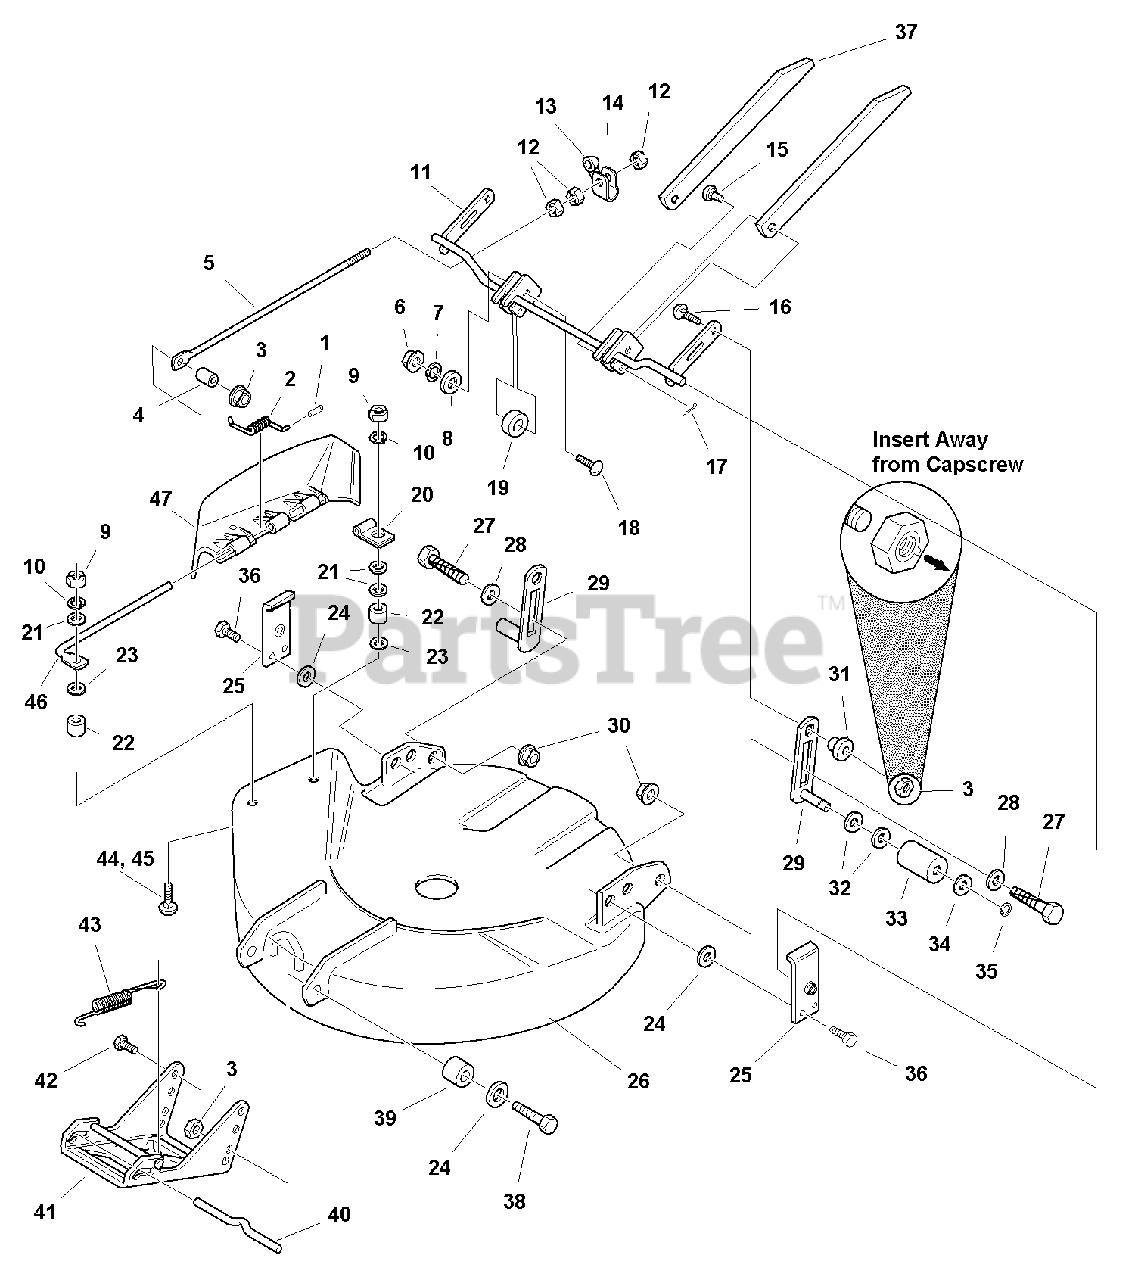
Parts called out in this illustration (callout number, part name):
1	CAP, Spring End
2	SPRING, Torsion
3	NUT, Hex, ALUM Lock, 3/8
5	ROD, Adjustment
6	NUT, Hex, 5/16-18
7	LOCKWASHER, 5/16
9	NUT, Hex, 1/4-20 ESNA
11	ARM ASSEMBLY, Mower
12	JAMNUT, Hex, 3/8-16
13	SPACER
15	PIN, Locking
16	CARRIAGE BOLT, 3/8-16 x 1-1/2
17	PIN, Retaining
18	CARRIAGE BOLT, 5/15-18 x 1-1/4
21	WASHER, Plain (1 Required for Export)
22	SPACER (Export)
23	PUSHNUT, 1/4
24	WASHER, Flat, 3/8
25	PLATE, Pivot Support
26	HOUSING ASSEMBLY, 30" (Orange)
26	HOUSING ASSEMBLY, 30" (Red)
26	HOUSING ASSEMBLY, 30" (Black)
27	BOLT, Shoulder, 3/8-16 X 1.34
28	WASHER, Flat
29	SUPPORT ASSEMBLY, Roller
30	NUT, Hex, Flange, Whizlock, 3/8-16
31	NUT, Hex Adjusting, .99 DIA .687
32	WASHER, 5/8
34	WASHER, 21/32 x 1-1/8 x 1/16
35	RING, Retaining
36	CAPSCREW, Taptite, 5/16-18 x 3/4
37	BAR, Mower Transport
38	CAPSCREW, Hex, 3/8-16 x 1-3/8
40	ROD, Latch, Hitch
41	HITCH ASSEMBLY
42	CAPSCREW, Hex Head, 3/8-16 x 1
43	SPRING, Extension
44	CARRIAGE BOLT, 1/4-20 x 3/4
45	CARRIAGE BOLT, 1/4-20 x 1-1/4 (Export)
46	ROD, Deflector
47	DEFLECTOR, Plastic
